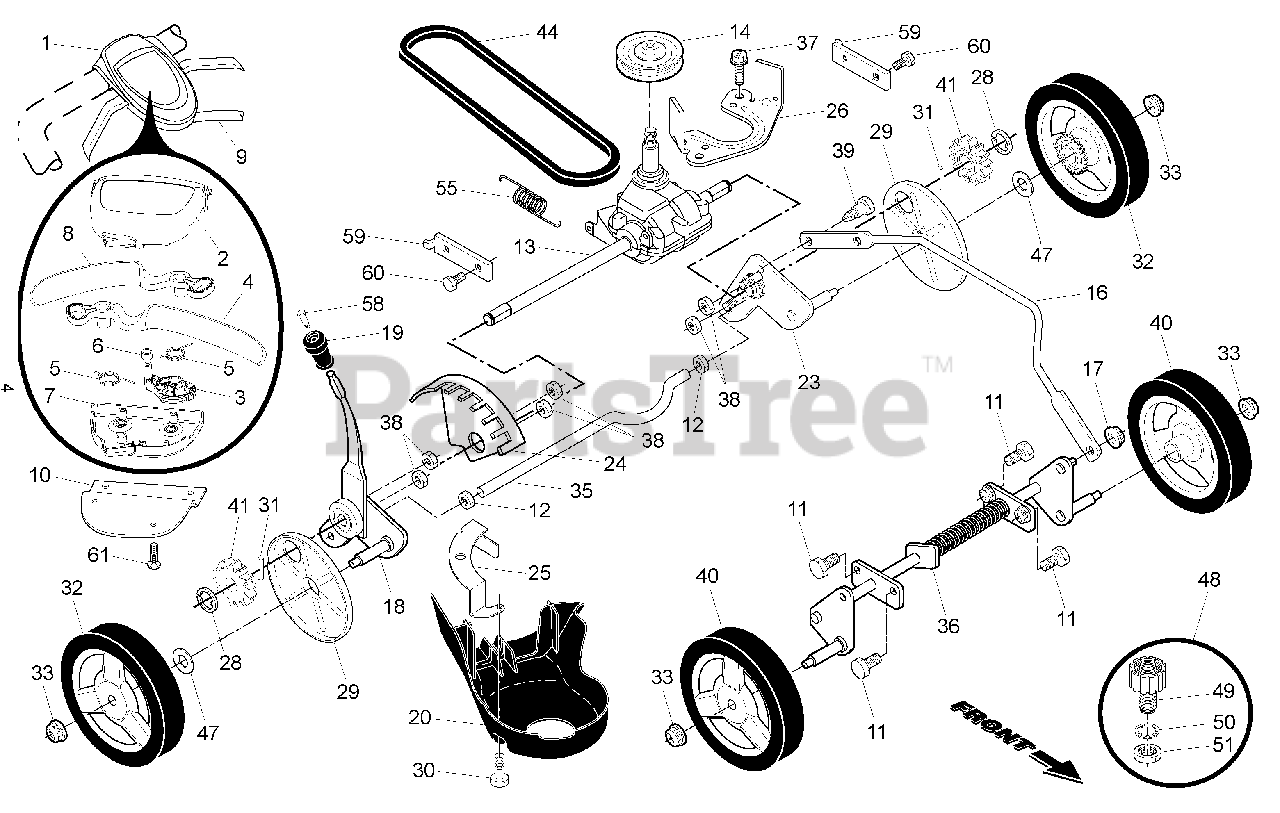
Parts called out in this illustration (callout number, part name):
1	Drive Control Assembly
2	Cover, Top
4	Lever, Drive Control, LH
5	Spring, Return
7	Cover, Bottom
8	Lever, Drive Control, RH
9	Cable, Drive
10	Mounting Bracket, Drive Control
13	Gear Case Assembly, Complete
14	Pulley, Drive
16	Rod, Connecting
17	Nut, Hex
18	Selector Assembly
19	Knob, Wheel Adjuster
20	Debris Shield
23	Wheel Axle Assembly, LH
24	Bracket, Height Adjustment
25	Mounting Bracket, Debris Shield
26	Belt Keeper
28	E-Ring 7/16
29	Cover, Dust, Wheel
31	Pawl, Drive
32	Wheel & Tire Assembly, Rear
33	Nut, Flangelock 3/8-16
35	Axle, Rear
36	Axle, Front
37	Screw, Hi-Lo Thread, 12 x 5/8
40	Wheel & Tire Assembly, Front
44	Belt, Drive
47	Washer, Flat
48	Kit, Water Washout Assembly
49	Fitting, Water Washout
50	Washer, Lock, Internal Tooth
51	Locknut, Hex, with O-Ring
55	Spring, Tension
58	Bolt, Shoulder
59	Support Bracket
60	Bolt, Hex Head
